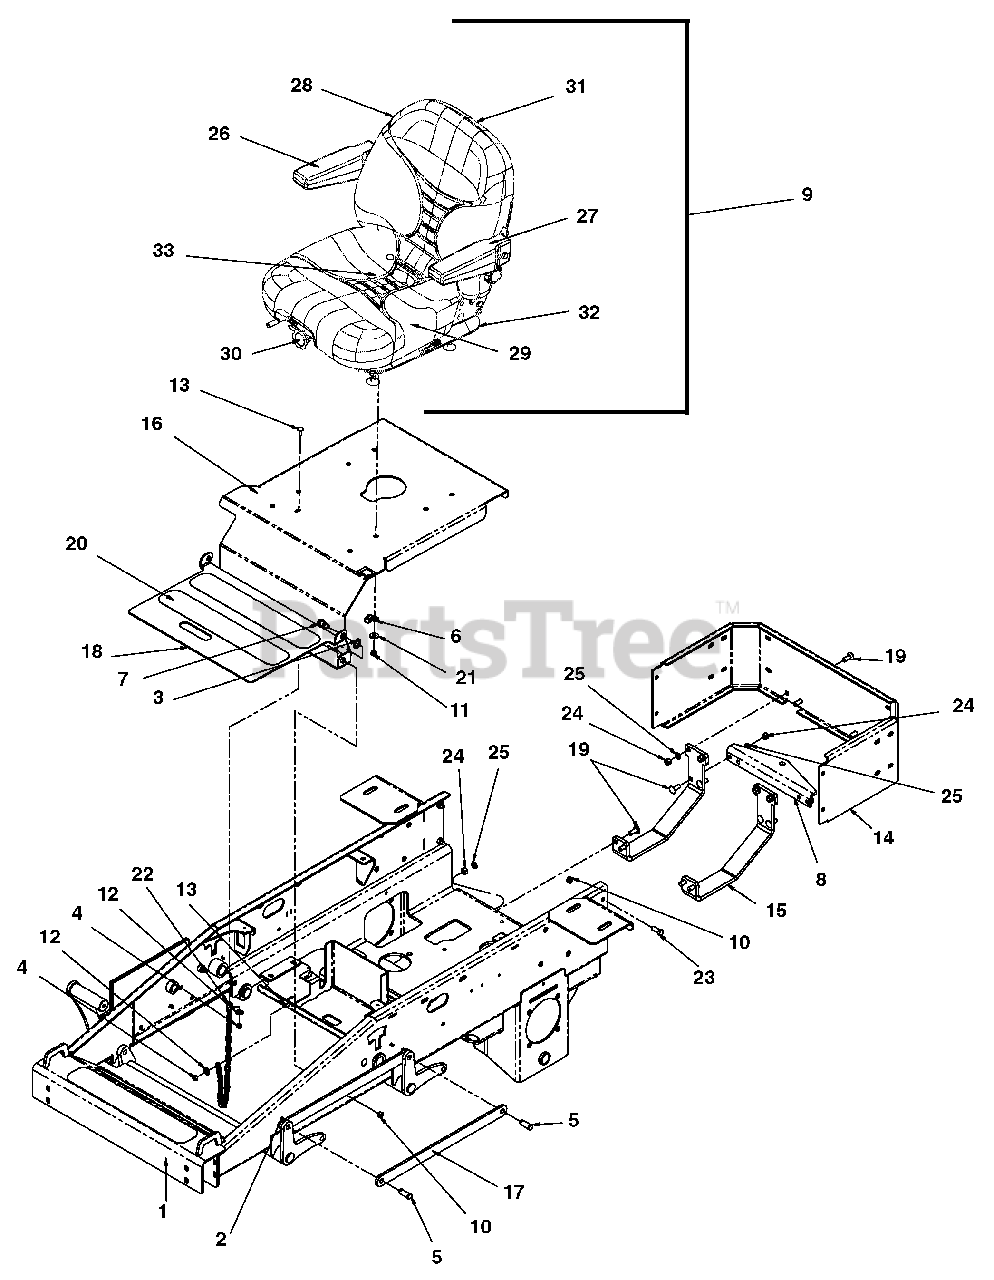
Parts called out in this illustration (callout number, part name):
1	WLDT, FRAME (PAINTED ARIENS)
2	RING, RUE .500 X .062 X 1.420
3	WASHER, .510X1.00X.068 NYLON
4	@NUT-LK-NYL .250-20 YWZC
5	PIN, CVS .500X1.25X1.02 Y
6	P-CLIP, .500 INSULATED
7	BOLT, 1/2X1.06X3/8-16 SLD 5 Y
8	PLATE, HITCH
9	SEAT-SUSP-LT GRY-SEAT BLT BUSH
10	NUT, .38-16 LOW CROWN LK ACORN
11	LOCKNUT, 5/16-18 CROWN Y
12	WASHER, .250 REG FLAT Y
13	BOLT, 1/4-20X.750 CRG 5 Y
14	PLATE, REAR GUARD (ARIENS)
15	BRACE, BENT ARM HITCH (ARIENS)
16	ARIENS SEAT PLATE W/DECALS
17	PLATE, ARM CONNECTOR LINK
18	PLATE, FLOOR PAN (ARIENS)
19	@BLT-RDHDSHSQNK.38-16X1.0 G5YZ
20	TAPE, TRACTION 3.00 X 17.00
21	@WSHR-FL-STL.38X.875X.083 YWZC
22	CHAIN, .148 X 27 LIINKS
23	@BLT-HEX .38-16X1.00 GR5 YWZC
24	@NUT-HEX .31-18 YWZC
25	@WSHR-LK .38X.094 REG YWZC
26	KIT-RH ARMREST ASSEMBLY REPLAC
27	KIT-LH ARMREST ASSEMBLY REPLAC
28	KIT-BACK CUSHION-LIGHT GRAY
29	KIT-SEAT CUSHION-LIGHT GRAY
30	KIT-SEAT KNOB
31	KIT-SEAT BACK PANEL
32	KIT-SEAT SLIDE
33	KIT-SPRING AND SADDLE
